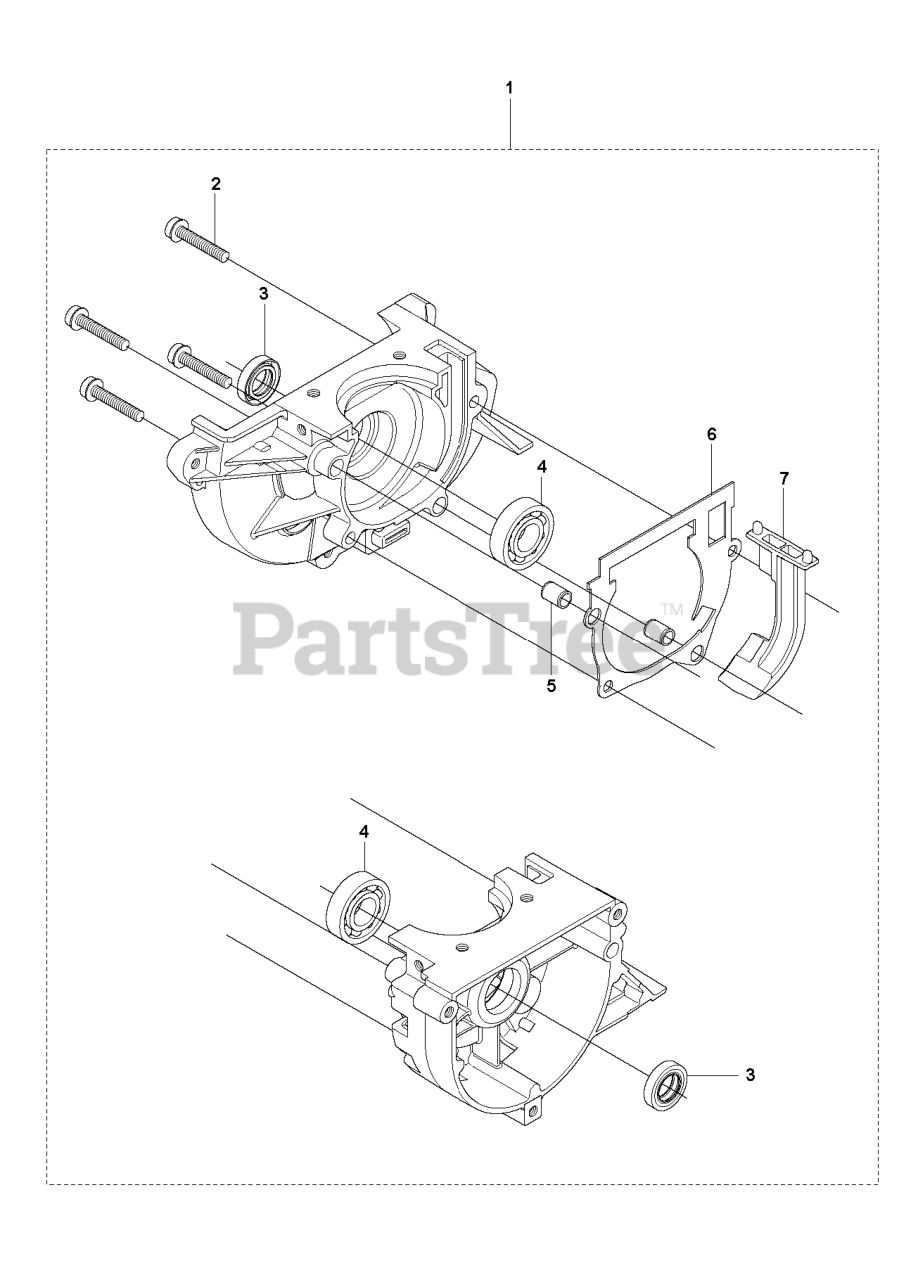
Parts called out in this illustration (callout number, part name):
1	CRANKCASE ASSY SPARE
3	SEALING RING
6	GASKET CRANKCASE
